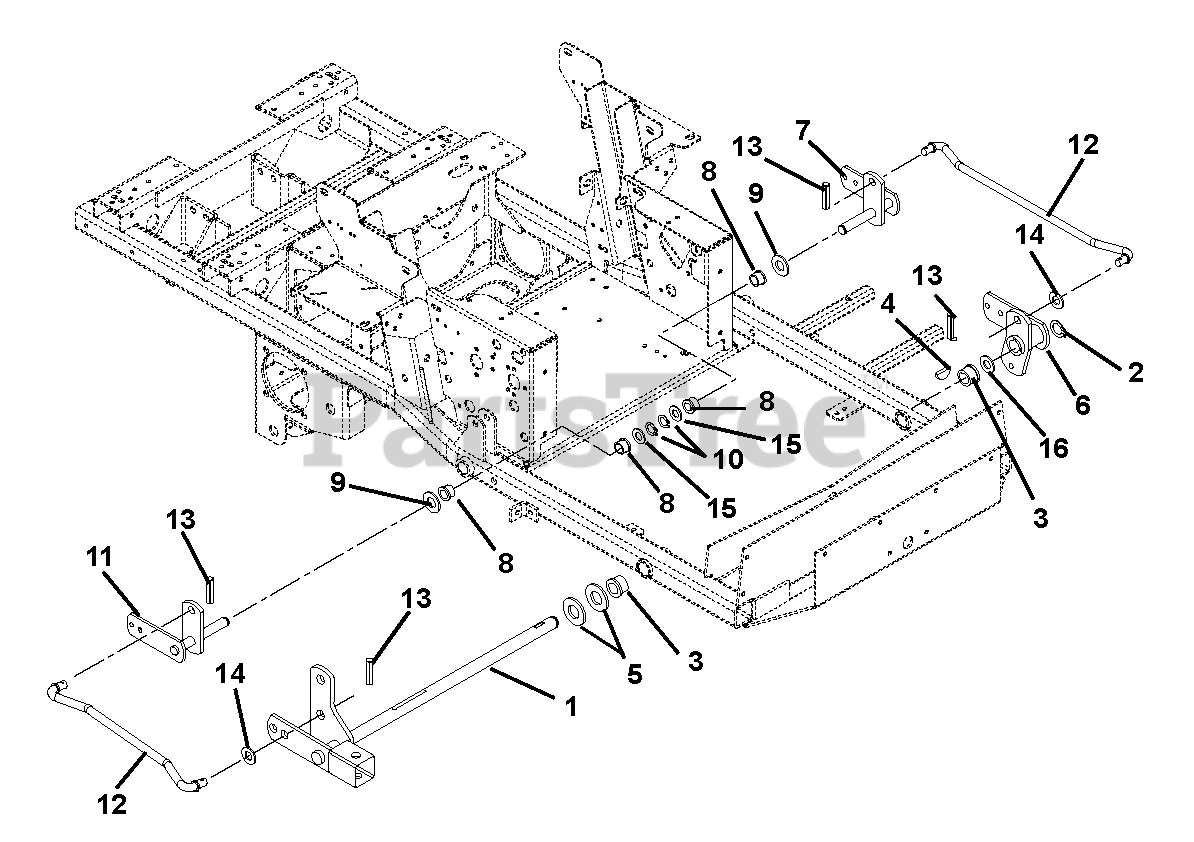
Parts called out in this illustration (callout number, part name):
1	Lift, Mower
2	Ring, Retaining External 1.00 x .078
3	Bushing, Flange 1.00 x 1.12 x .75 x 1.375
4	Key, Woodruff .25 x 1.00
5	Washer, Flat Steel 1.062 x 2.00 x .134
6	Weldment, Lift Arm-Front
7	Weldment, Rear Lift Arm-Left Hand
8	Bushing, Flange Nylon .762 x 1.0 x .58 x 1.48
9	Washer, Hardened Steel .758 x 1.23 x .031
10	Ring-Retaining-External .689 x .077
11	Weldment, Rear Lift Arm- Right Hand
12	Rod, Lift Assist 19.35"
13	Pin, Roll .25 x 1.25 Stainless Steel
14	Washer, Flat Steel .630 x 1.25 x .062
15	Washer, Flat Steel .755 x 1.25 x .125
16	Washer, Hardened Thrust 1.00 x 1.55 x .03
